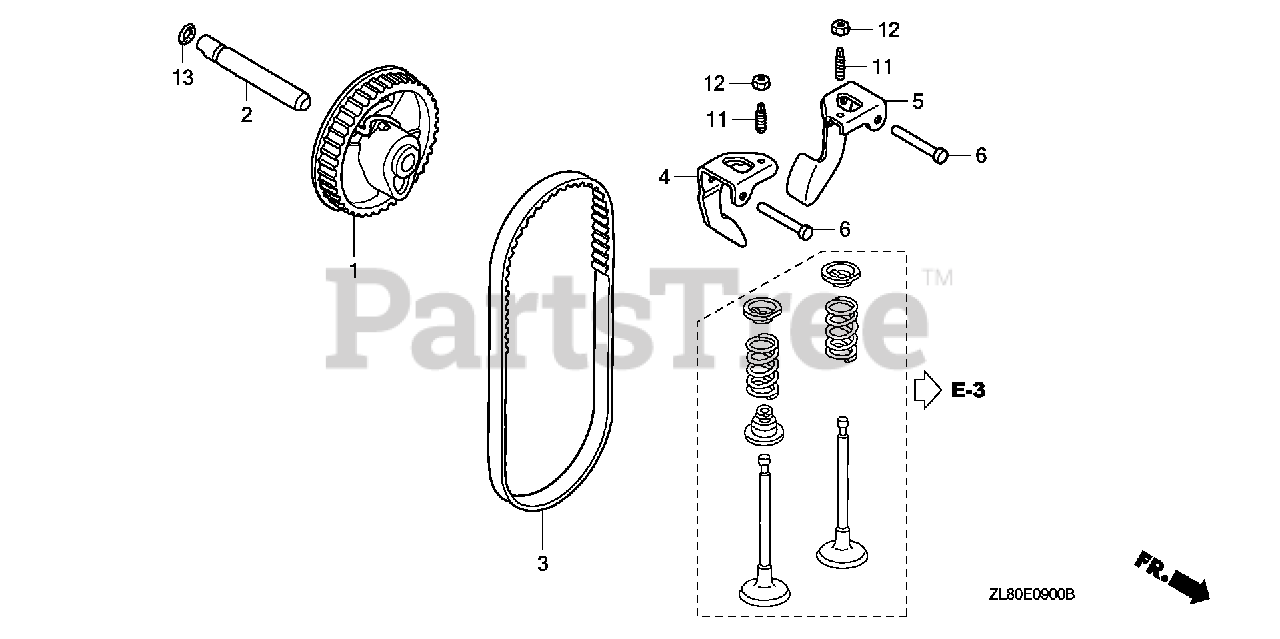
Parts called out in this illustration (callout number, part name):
1	PULLEY, CAMSHAFT
2	SHAFT, CAM PULLEY
3	BELT, TIMING (84HU7 G-200)
4	ARM, IN. VALVE ROCKER
5	ARM, EX. VALVE ROCKER
6	SHAFT, ROCKER ARM
11	SCREW, TAPPET ADJUSTING
12	NUT, TAPPET ADJUSTING
13	O-RING (6.8X1.9) (ARAI)
